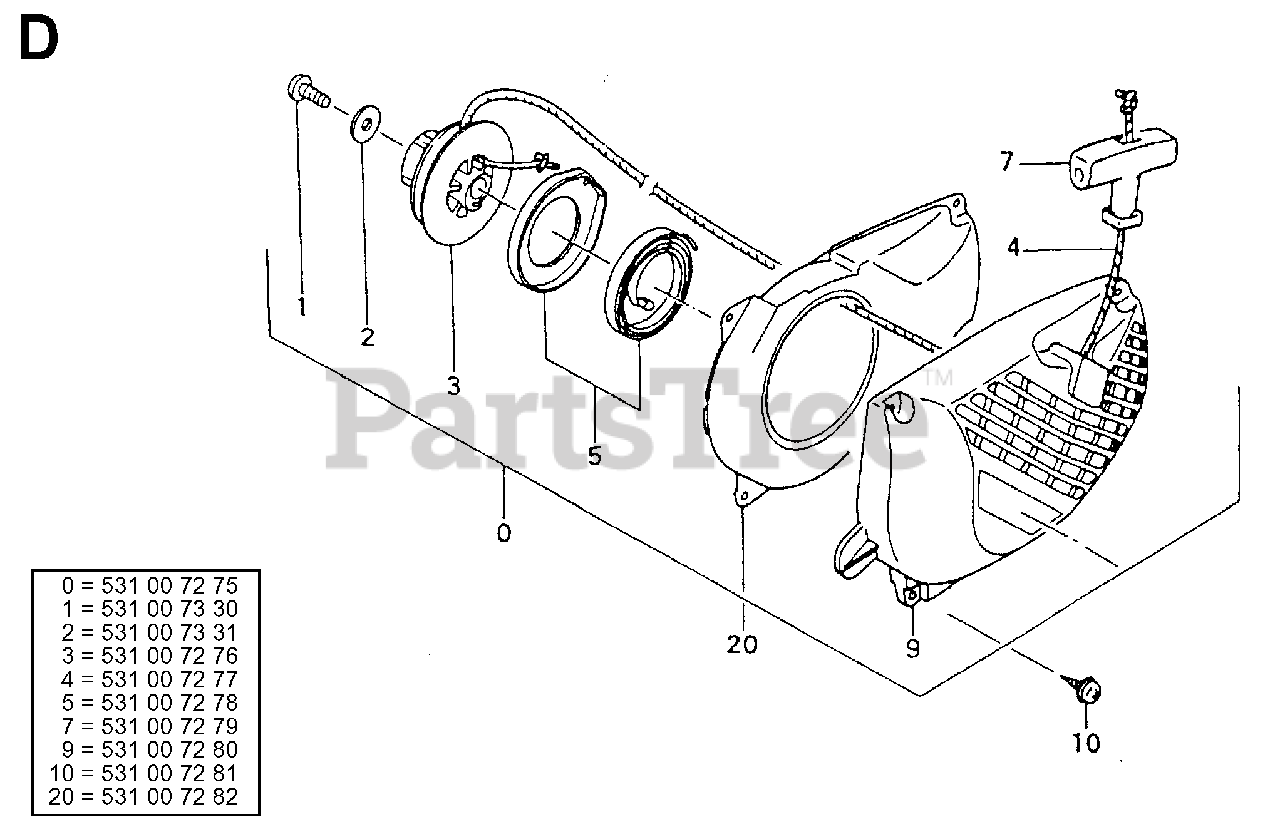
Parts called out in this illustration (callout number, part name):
3	STARTER PULLEY
4	STARTER ROPE
5	RETURN SPRING
9	STARTER HOUSING
20	AIR CONDUCTOR
